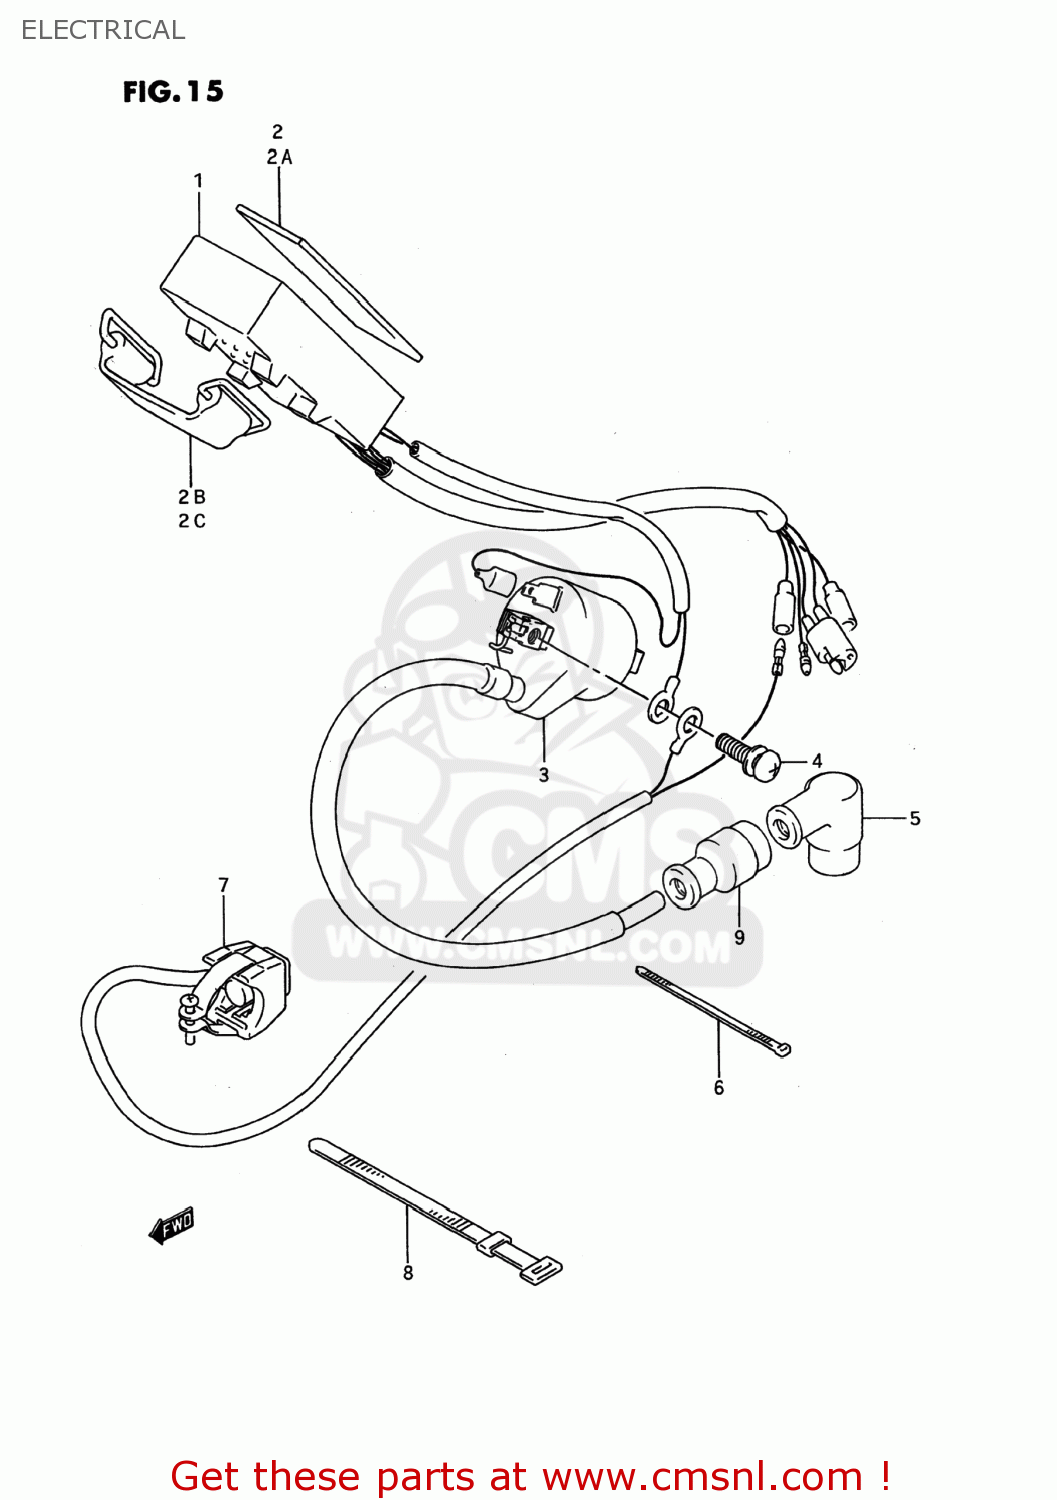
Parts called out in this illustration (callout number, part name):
1	CDI UNIT
2	PROTECTOR(170X95X3.0)
2A	PROTECTOR(170X95X3.0)
2B	BAND
2C	BAND(L:65)
3	COIL ASSEMBLY,IGNITION
4	SCREW
5	CAP,SPARK PLUG
6	CLAMP
7	SWITCH ASSEMBLY
8	CLAMP(L:120)
9	SEAL,HIGH TENSION CORD
